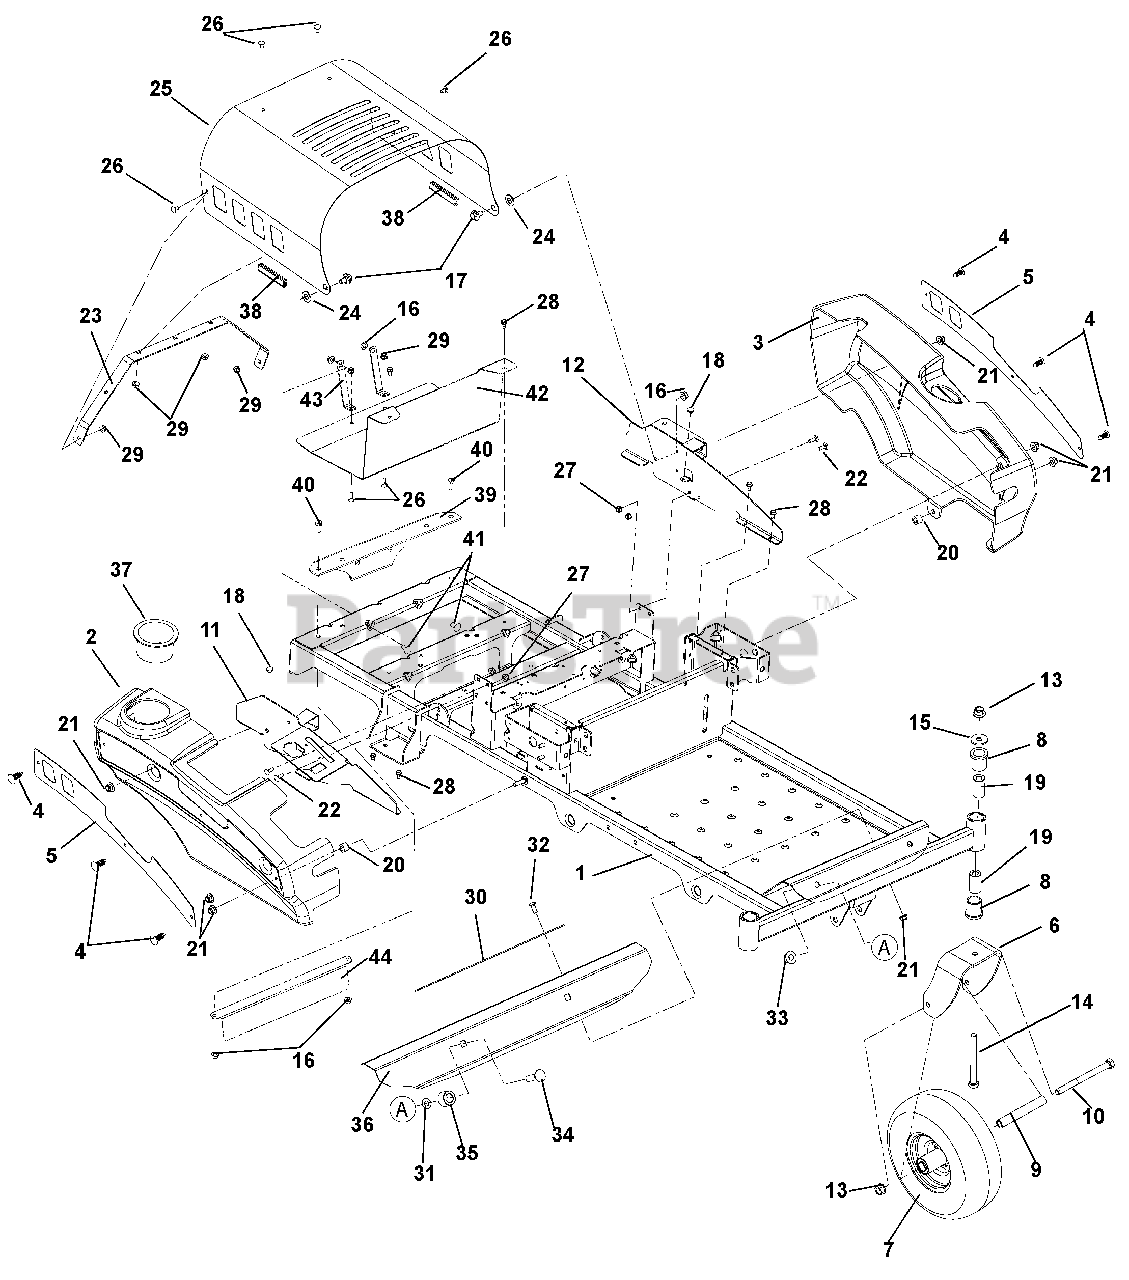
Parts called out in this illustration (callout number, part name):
1	FRAME, WELDMENT ZOOM 2012
2	FENDER, RH
3	FENDER, LH
4	RIVET, .25 NYLON PANEL
5	PLATE, FENDER
6	WMT, CASTER FORK
7	TIRE/WHEEL ASSY, 11X4-5
8	BSHG-FLG 1.00X1.25X1.50X1.50
9	SPACER, ROLLED WHEEL
10	@BLT-HEX .50-13X6.50 GR5 YWZC
11	WLDMT, RH FENDER MOUNT
12	WLDMT, LH FENDER MOUNT
13	@NUT-LK-TOP-FLG .50-13 YWZC
14	@BLT-HEX .50-13X5.00 GR5 YWZC
15	WSHR-FL-STL.511X1.441X.125 YWZ
16	@NUT-LK-TOP-FLG .38-16 YWZC
17	BOLT-SHLDR .375-16X.150
18	BUMPER GROMMET
19	SPACER, CASTER .50X1.00X1.84
20	BSHG-SLV .391X.688X.52 PM
21	@NUT-LK-NYL-FLG .31-18 YWZC
22	@BLT-RDHDSQNK .25-20X.75 G5YZ
23	BRACE, HOOD
24	WSHR-FL-NYL .518X1.000X.080
25	HOOD, ZOOM
26	@BLT-RDHDSQNK .25-20X.50 G5YZ
27	@NUT-LK-NYL-FLG .25-20 YWZC
28	SCR-TAP .25-20X.50 HWH TR YWZ
29	@NUT-LK-TOP-FLG .25-20 YWZC
30	GRIP, ADHESIVE (1" X 16" BLK)
31	NUT-PUSH, .50
32	@BLT-RDHDSQNK .31-18X.75 G5YZ
33	@NUT-LK-NYL-FLG .50-13 YWZC
34	@BLT-RDHDSQNK .50-13X1.75 G5YZ
35	TUBE, UPPER CONTROL PIVOT
36	FOOTREST
37	CUPHOLDER, SNAP-IN 3.75OD
38	EDGING, CLUTCH PADDLE - 2.00"
39	PLATE, BBZ HITCH KIT PLATE
40	@BLT-HEX .38-16X1.00 GR5 YWZC
41	@BLT-RDHDSQNK .38-16X1.00 G5YZ
42	GUARD, HEAT SHIELD (ZOOM/ZT)
43	STRAP, HEAT SHIELD (ZOOM/ZT)
44	GUARD, HOT SURFACE (ZOOM/ZT)
